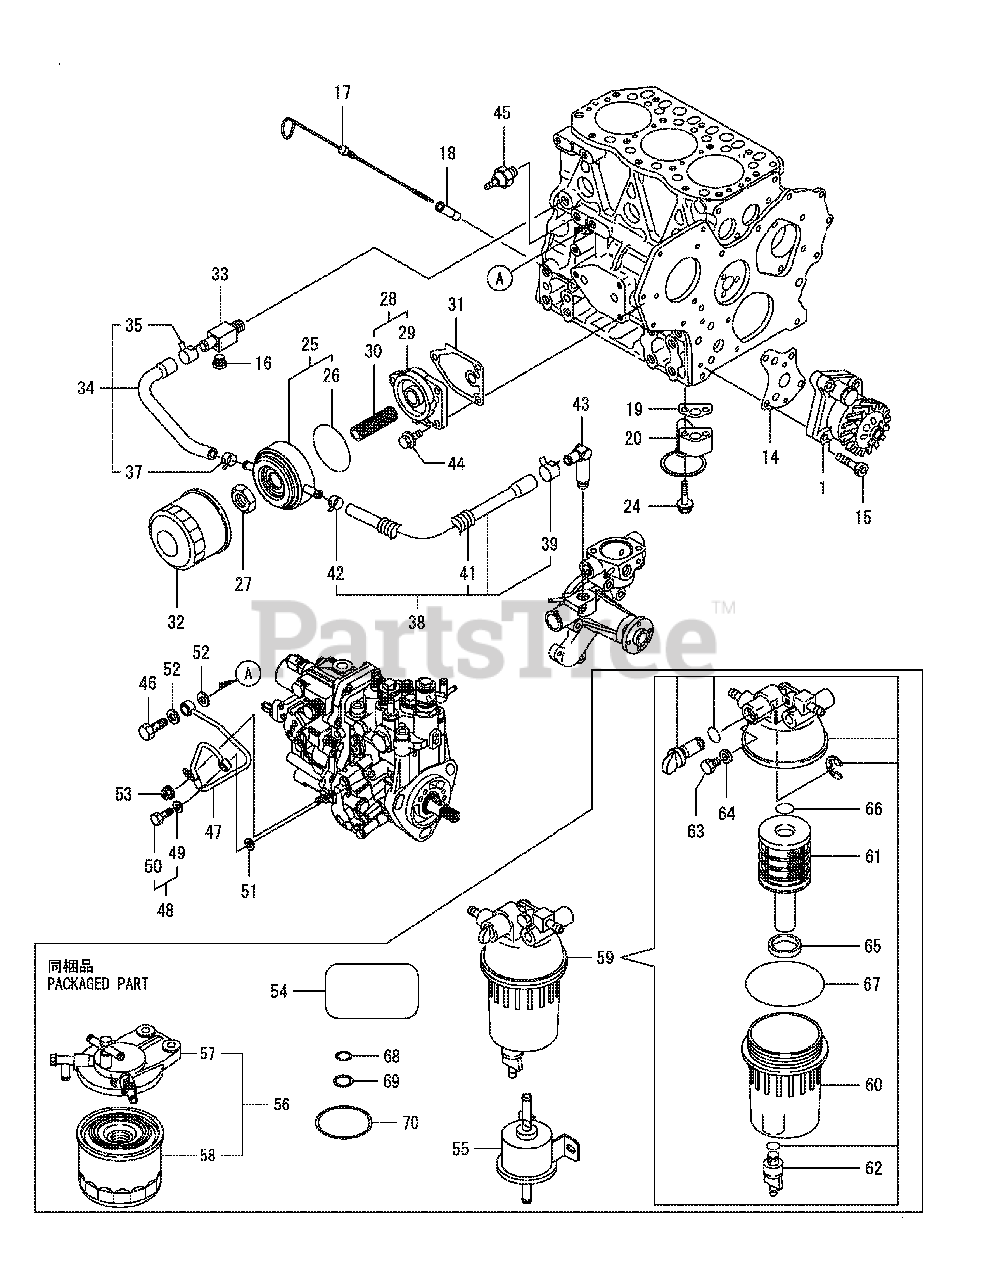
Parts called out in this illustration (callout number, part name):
1	Lubrication Oil Pump Assembly
17	Lubrication Oil Dipstick
18	Dipstick Guide
20	Oil Inlet Pipe Assembly
25	Lubrication Oil Cooler Assembly
27	Oil Cooler Nut
28	Filter Bracket Assembly
29	Filter Bracket
32	Filter, 80 x 80L
34	Cooler Inlet Pipe
38	Cooler Outlet Pipe
41	Corrugated Tube
45	Oil Pressure Switch
46	Joint Bolt, M10
47	Lubrication Oil Pipe Assembly
48	Joint Bolt Assembly
49	Seal Washer, 8S
51	Seal Washer, 8S
54	Fuel Oil Label
55	Fuel Feed Pump Assembly
56	Fuel Filter Assembly
57	Filter Bracket
59	Seperator Assembly
63	Air Vent Valve
66	O-Ring, 1A P-16.0
67	O-Ring, 1A G-75.0
68	O-Ring, 4D P-7.0
69	O-Ring, 4D P-16.0
70	O-Ring, 4D G75
